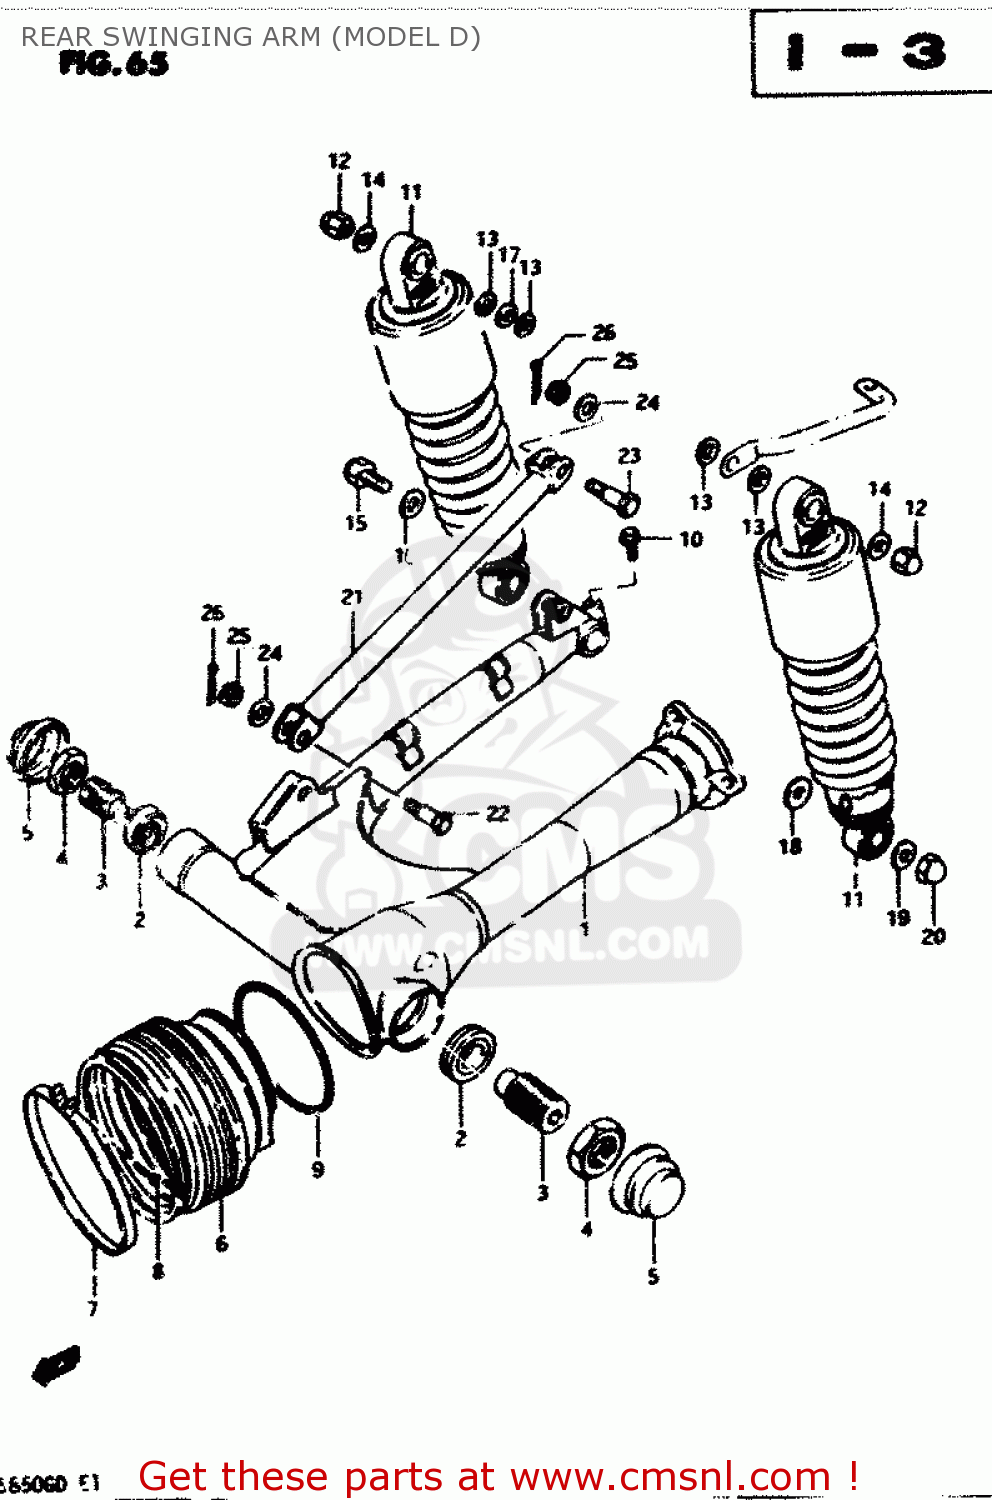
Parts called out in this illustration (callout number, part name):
1	SWING ARM SET,REAR (B
2	BEARING(17X40X13.25)
3	BOLT,REAR SWING ARM PIVOT
4	NUT
5	CAP,REAR SWING ARM PIVOT
6	BOOT,PROPELLER SHAFT
7	CLAMP
8	SCREW 4X25
9	SPRING,PROPELLER SHAFT
10	BOLT
11	ABSORBER ASSY,RR SHOCK
12	NUT
13	WASHER
14	WASHER
15	BOLT 12X33
16	WASHER (12.5X24X1.6)
17	WASHER (12.5X24X3.2)
18	WASHER
19	WASHER
20	NUT, LOWER LH
21	TORQUE LINK,REAR
22	BOLT
23	BOLT(10X39)
24	WASHER
25	NUT
26	PIN 20X20
